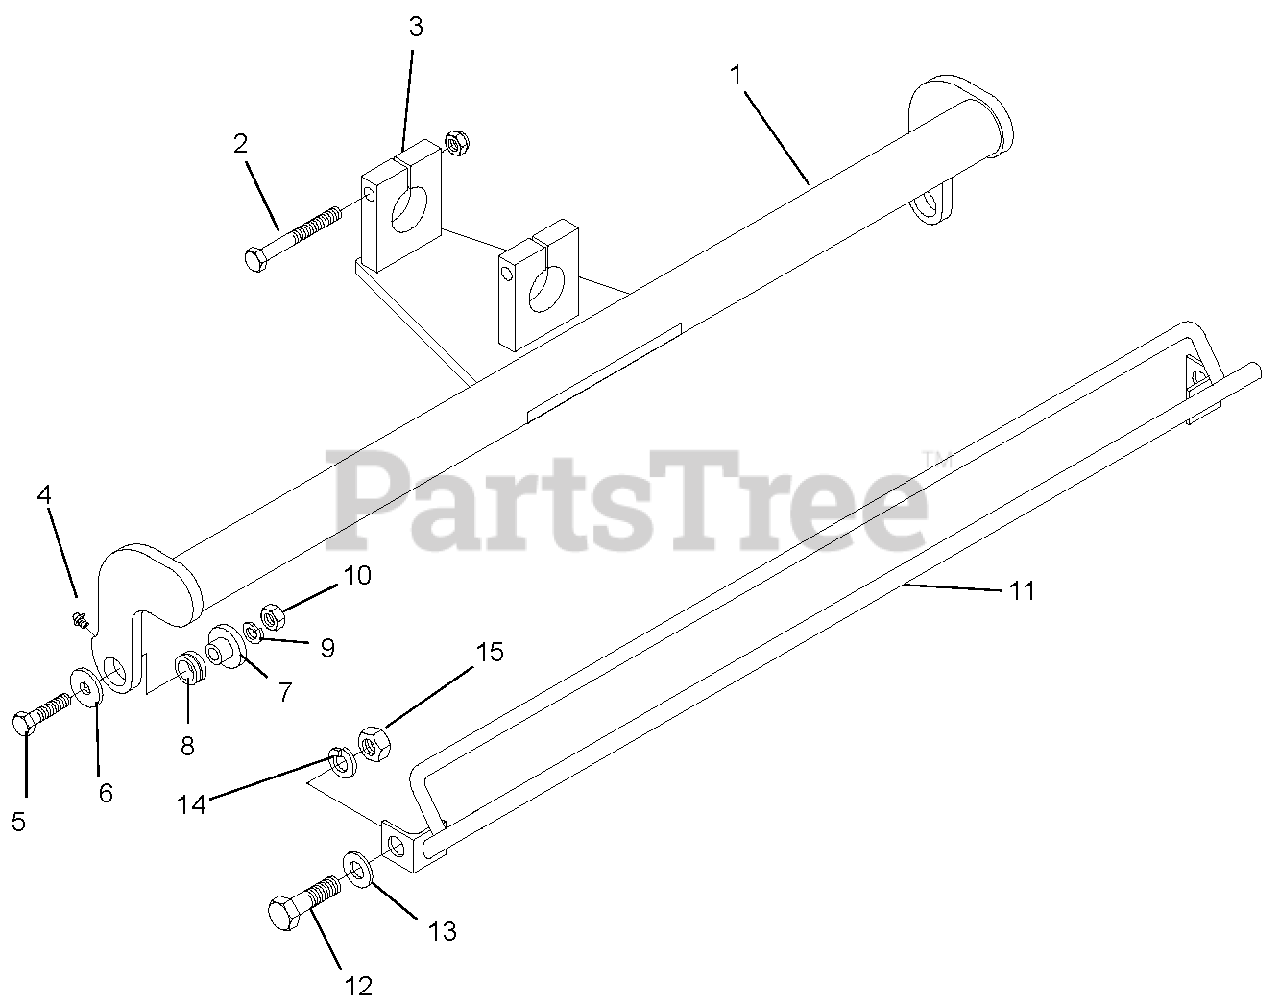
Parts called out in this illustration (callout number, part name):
1	Weldment, Piviting Arm
2	Cap Screw, Hex Head .375-16 x 3
4	Fitting, Grease .187 Drive
5	Cap Screw, Hex Head .375-16 x 1.50
6	Washer, Flat .375 SAE
7	Bushing, Pivot Arm
8	Race, Pivot Bushing
9	Washer, Lock .375
10	Nut, Jam .375-16
11	Toe Guard Assembly
12	Cap Screw, Hex Head .50-13 x 1.5
13	Washer, Flat .50
14	Washer, Lock .50
15	Nut, Hex .50
